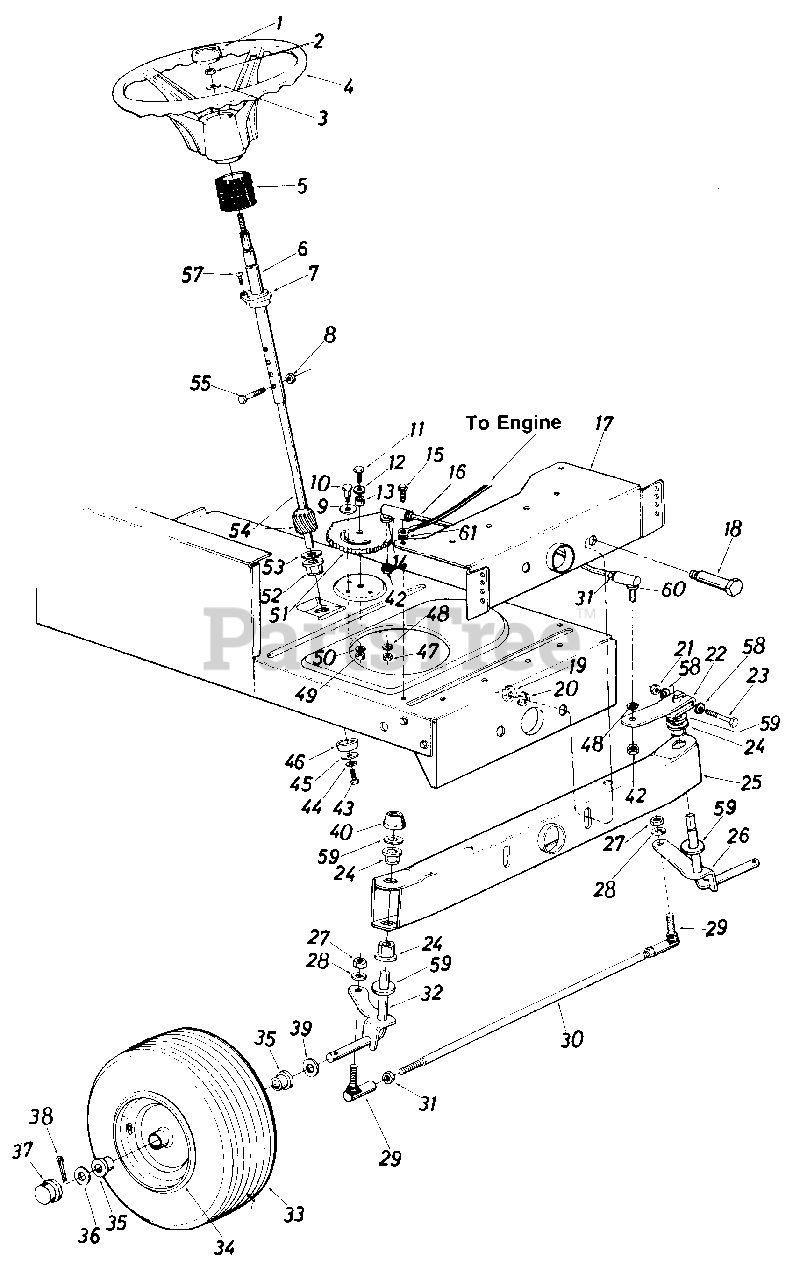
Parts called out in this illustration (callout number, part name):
1	Steering Wheel Cap
2	Hex L-Nut 5/16-24 Thd.
3	Belleville Wash. .345" I.D.
4	Steering Wheel
5	Steering Bellow 4.5"
6	Steering Column Ass y.
7	Flange Bearing .890 I.D. x 1.36 O.D.
8	Hex L-Nut 1/4-20 Thd.
9	Fl-Wash. .438" I.D. x 1.37" O.D.
10	Shoulder Bolt .437" Dia. x .35 Lg. 5/16-18 Thd.
11	Hex Bolt 3/8-24 x 1.0" Lg. (Grade 5)
12	Bell-Wash. .4" I.D. x 1.13" 0. D.
13	Spacer .380" I.D. x .625" O.D. x .227
14	L-Wash. 3/8" I.D.
15	Hex Wash. Hd. Self-Tap Scr.
16	Steering Drag Link
17	Front Pivot Brkt.
18	Shoulder Bolt .498" Dia. x 2.04 Lg. 3/8-16 Thd.
19	Hex Nut 3/8-16 Thd.
20	L-Wash. 3/8" I.D.
21	Hex Cent. L-Nut 5/16-24 Thd.
22	Steering Arm Front Axle
23	Hex Bolt 5/16-24 x 2.00" Lg. (Grade 5)
24	Hex Flg. Brg. .634 I.D.
26	Front Axle Ass'y. L.H.
27	Hex Nut 3/8-24 Thd.
28	L-Wash. 3/8" I.D.
29	Ball Joint 3/8-24 Thd.
30	Tie Rod
31	Hex Jam Nut 3/8-24 Thd.
32	Front Axle Ass'y. R.H.
33	Wheel Ass'y. Comp.
34	Front Wheel Rim Only
35	Bearing
36	Fl-Wash. .635 I.D. x 1.59" O.D.
37	Front Wheel Hub Cap
38	Cotter Pin 1/8" Dia. x 1.25
39	Fl-Wash. .640" I.D. x 1.24" O.D.
40	Push Cap 518" Dia. Rod
42	Hex Jam Nut 3/8-24 Thd.
43	Hex L-Bolt 5/16-18 x .62"
44	L-Wash. 5/16" I.D.
45	Fl-Wash. .33" I.D. x 1.25" O.D.
46	Spacer (Plastic)
47	Hex Nut 3/8-24 Thd.
48	L-Wash. 3/8" I.D.
49	Hex Nut 5/16-18 Thd.
50	L-Wash. 5/16" I.D.
51	Steering Gear Segment
52	Hex Flg. Brg. .634 I.D.
53	Fl-Wash. (Hardened)
54	Steering Shaft Lower
55	Hex Bolt 1/4-20 x 1.25" Lg
57	Oval Hd. Cr. Sunk Scr. #10 x 5/8" Lg.
58	Wave-Wash. .32" I.D. x .6 O.D.
59	Fl-Wash. (Hardened)
60	Drag Link Ball Joint 3/8-24 Thd.
61	Ext. L-Wash. 5/16" I.D.
